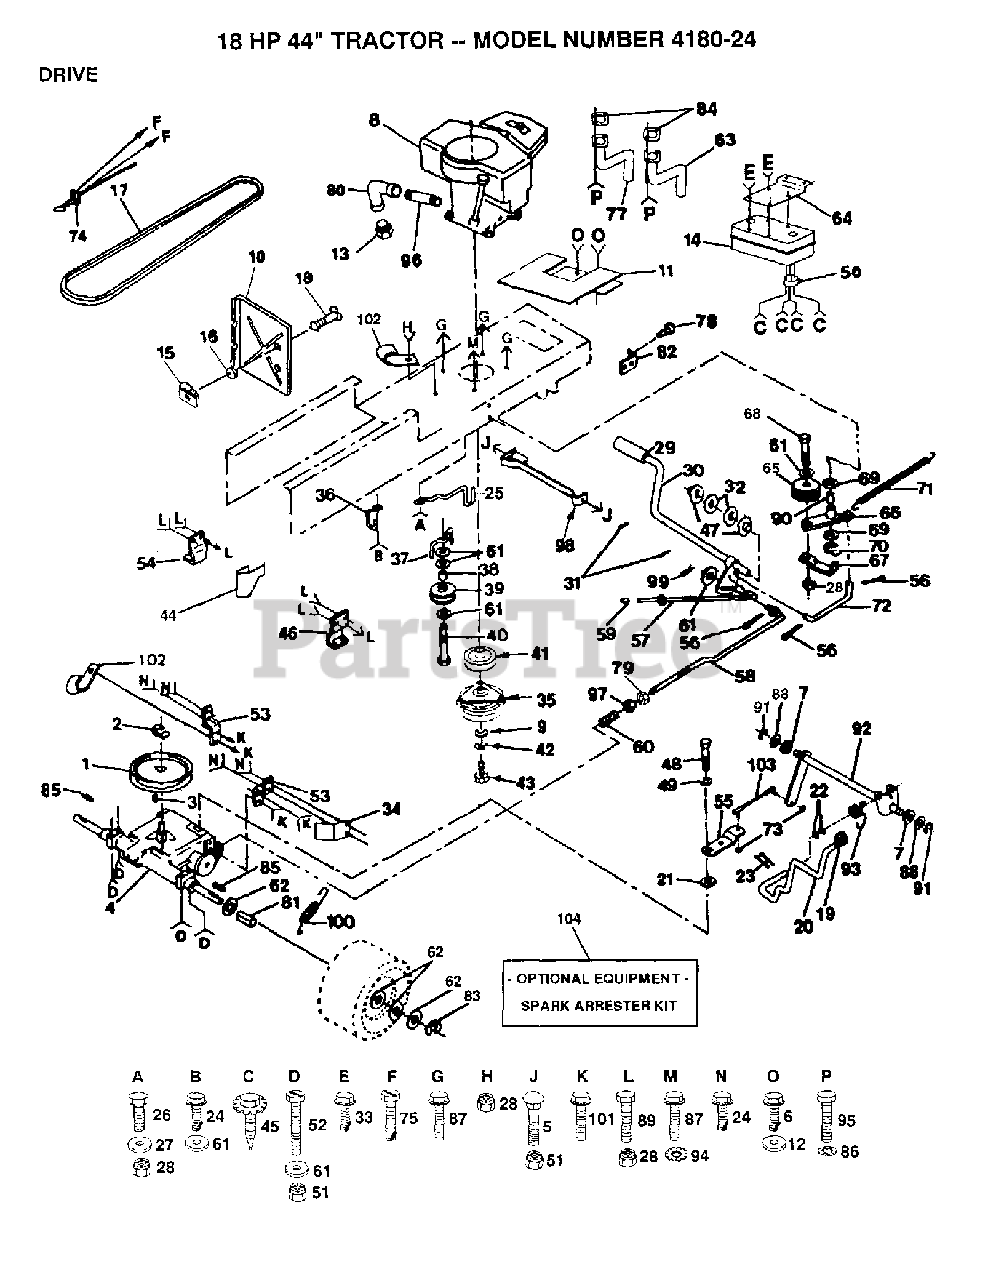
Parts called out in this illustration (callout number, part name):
1	PULLEY TRANSAXLE
3	KEY.WOODRUFF
4	TRANSAXLE NLA
5	BOLT
6	Screw, Lt
7	BUSHING.STEERING.ROD
10	SHIELD HEAT HYT
11	HEAT SHIELD
15	RECEPTACLE LT
16	RETAINER LT
17	BELT.GROUND.DRIVE
18	STUD 1/4 TURN
19	KNOB T (1/2-HOLE)
20	ROD SHIFTER
21	WASH-SHFT PLT LT
22	WASHER
23	PIN COTTER
25	KEEPER, BELT
26	BOLT
27	WASHER
28	LOCKNUT
29	PEDAL COVER
31	Drive Pin, 3/16 X 1"
32	WASHER LT
33	SCREW ST
34	KEEPER,BELT RH
36	BELT RETAINER
37	BELT KEEPER LT
38	SPACER T
39	FLAT IDLER PULLEY
41	ENGINE PULLEY
42	LOCKWASHER
44	KEEPER BELT LH
46	BRKT TRANS RH
47	BEARING.NYLON
49	WASHER PM
50	DEFL MUFFLER LTV
51	LOCKNUT
53	STRAP TORQUE
54	BRKT TRANS LH
55	ARM,SHIFT
56	COTTER PIN
57	ROD BRAKE PARK
58	ROD BRAKE
59	PLUNGER CAP
60	SPRING,ROD BRAKE
65	Idler Pulley
67	RETAIN BELT
68	Hex Bolt
69	WASHER LT
70	KLIP RING
71	SPRING, RETURN LT
73	NUT 1/4-28
74	THROTTLE CONTROL
79	NUT
80	ELBOW
81	SPACER HYT
82	BRACKET LT
83	E RING HYT
84	Poulan TBD
86	LOCKWASHER
88	WASHER D
90	BEARING LT (2 2)
91	KLIP RING
92	SHAFT,SHIFTER
93	SPRING,TORSION
94	LOCKWASHER
96	NIPPLE, PIPE 3/8NPT X 4-1/2
97	NUT
98	KIT RETAINER YTH
99	RETAINER M
100	SPRING T
101	Screw, Lt
102	CLIP T
104	SPARK ARREST
